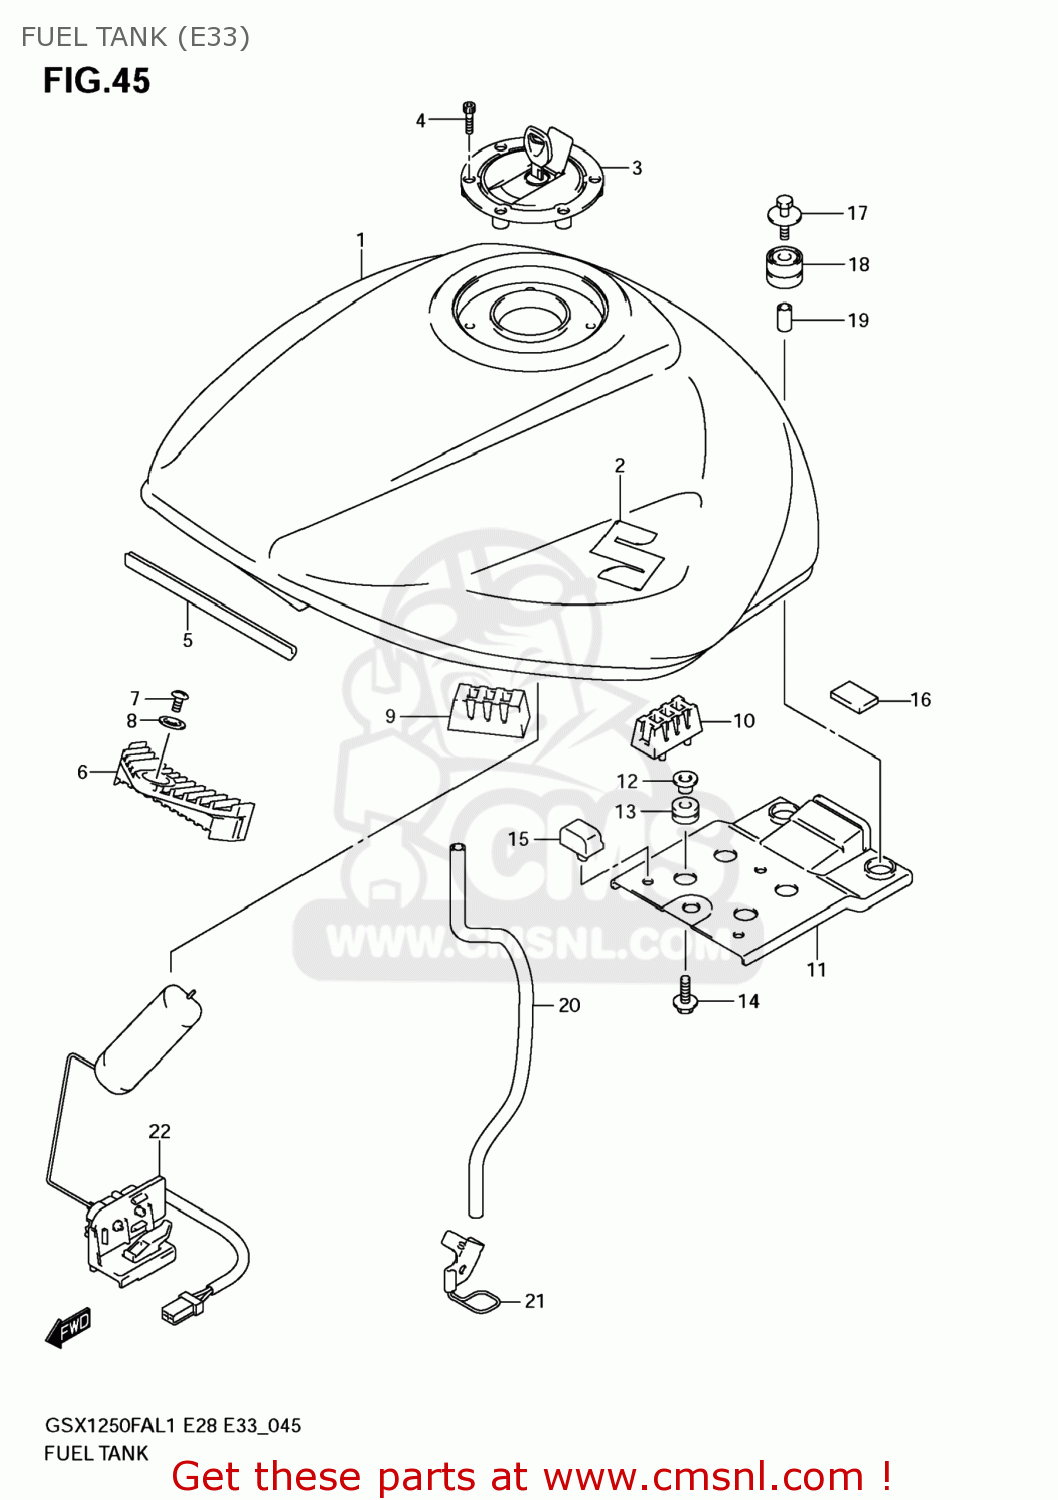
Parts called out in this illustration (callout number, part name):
1	TANK ASSY, FUEL
2	EMBLEM,S
3	CAP SET,FUEL TANK
4	BOLT(5X20)
5	MOLDING
6	CUSHION,FUEL TANK FR
7	SCREW
8	WASHER
9	CUSHION,SUPPORT(50X25X32)
10	CUSHION,TANK SIDE
11	BRACKET,FUEL TANK RR
12	WASHER
13	CUSHION
14	BOLT(6X20)
15	CUSHION
16	CUSHION,SIDE COVER BRACKET
17	BOLT(6X30)
18	CUSHION,FUEL TANK RR BRKT
19	SPACER(6.5X9X18)
20	HOSE,FUEL TANK DRAIN
21	GUIDE,DRAIN HOSE
22	GAUGE ASSY,FUEL LEVEL SENDER
